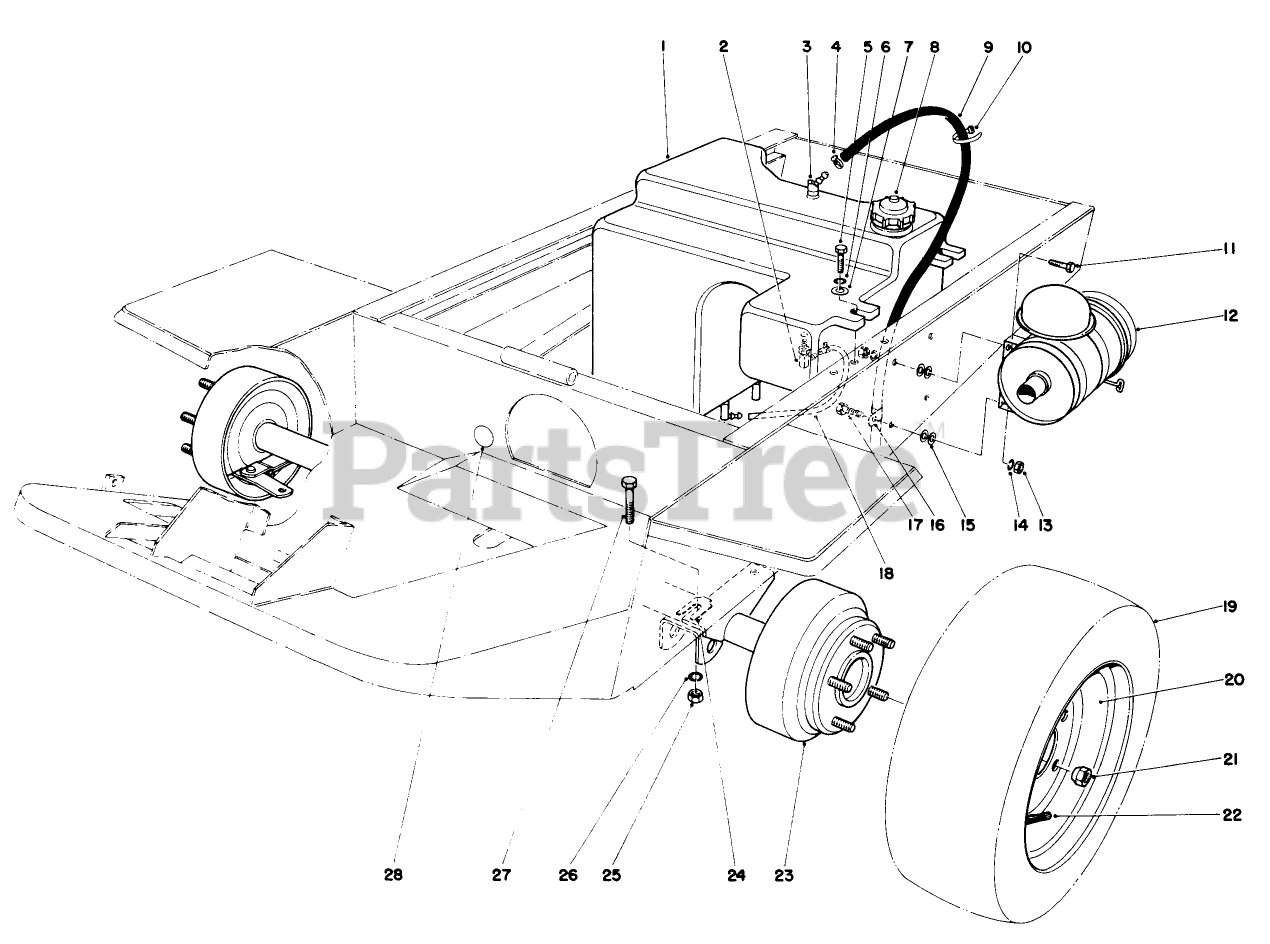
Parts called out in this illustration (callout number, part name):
1	Gas Tank (Incl. Ref. #2 & 3)
2	FITTING-ELBOW, 90 DEG
3	ELBOW
4	CLAMP-HOSE
5	SCREW-HH
6	WASHER-LOCK
7	WASHER
8	Gas Cap
9	GAS TANK VENT HOSE
10	Strap
11	SCREW-HH
12	AIR CLEANER KIT
13	NUT-HEX
14	WASHER-LOCK
15	WASHER-PLAIN
16	CLAMP-R
17	SCREW-HH
18	HOSE-FUEL
19	20 X 8.00 - 10 TIRE
20	WHEEL ASM
21	NUT-WHEEL
22	VALVE STEM AND CAP ASM
24	SHIM-AXLE
25	NUT-HEX
26	WASHER-LOCK
27	SCREW-HH
28	OIL DECAL
